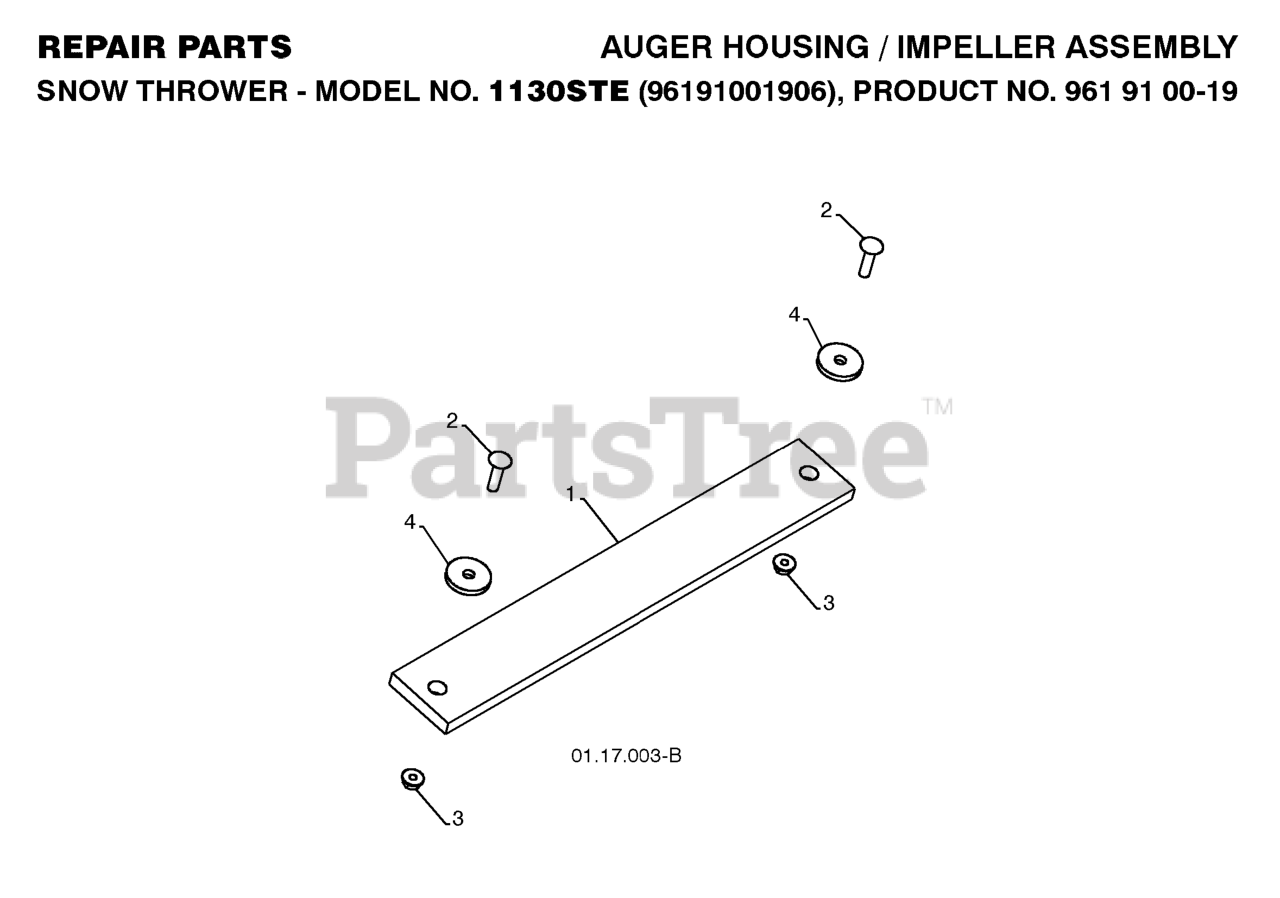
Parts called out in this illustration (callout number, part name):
1	WEIGHT AUGER HOUSING 30
2	BOLT.CARRIAGE.5/16-18
3	NUT.LOCK.5/16-18
4	WASHER.FLAT.34X1.38X22
